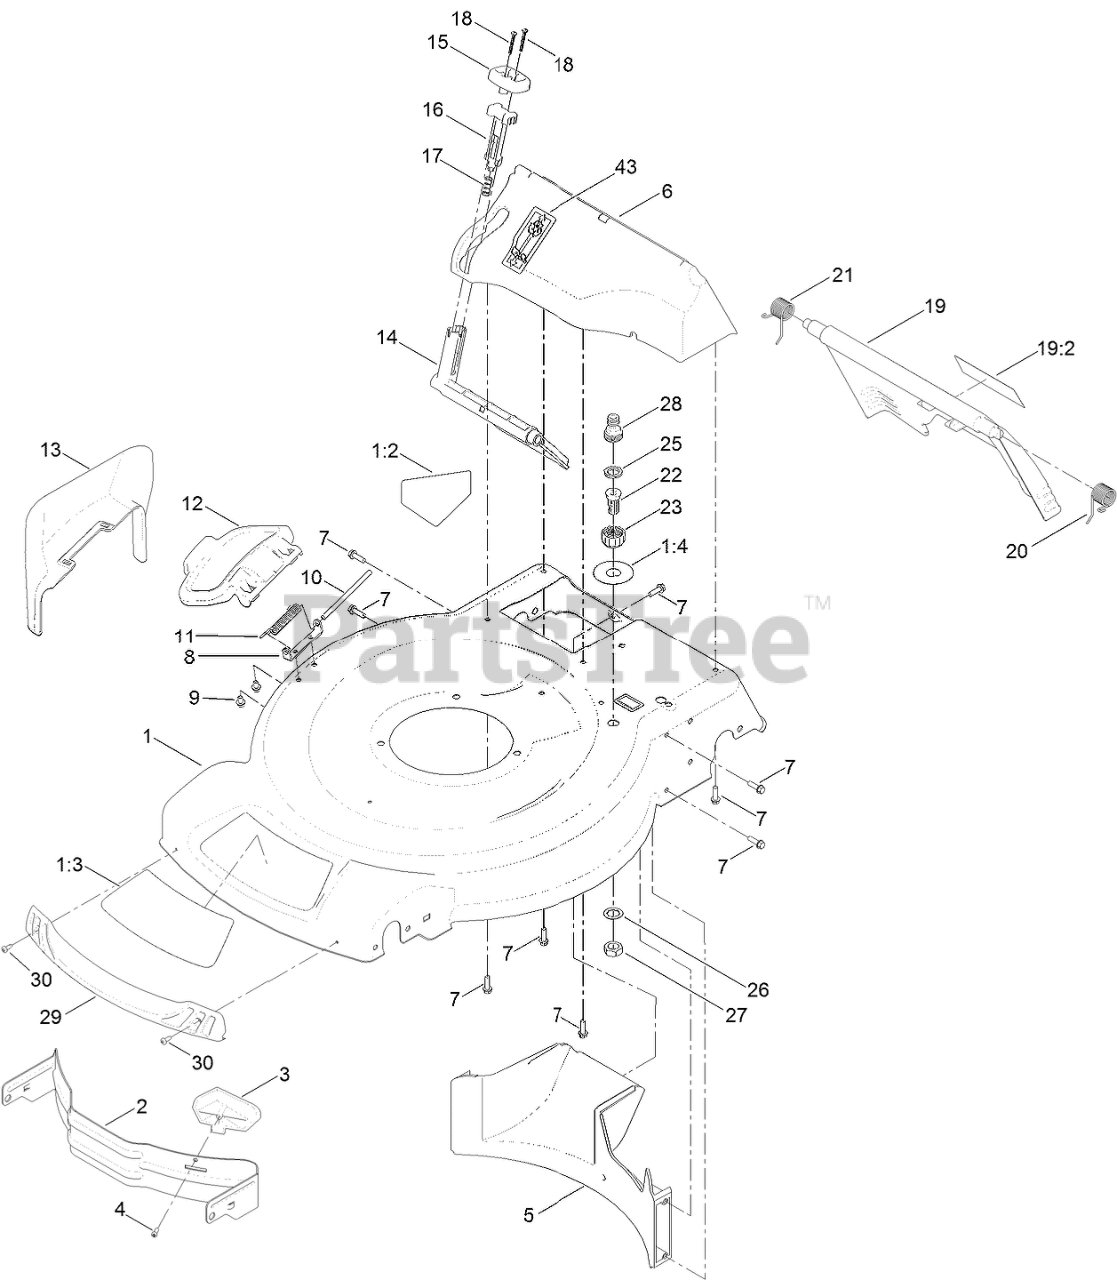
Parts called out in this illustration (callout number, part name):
1	HOUSING ASM
1:2	DECAL-DANGER
1:4	DECAL-PORT, WASHOUT
2	BAFFLE-FRONT
3	KICKER-FRONT
4	SCREW-PPH
5	BAFFLE-REAR
6	CHUTE-RECYCLE
7	SCREW-HWH
8	BRACKET-COVER
9	SCREW-HWH
10	ROD-COVER
11	SPRING-TORSION
12	DEFLECTOR-SIDE
13	CHUTE-DISCHARGE, SIDE
14	DEFLECTOR-RECYCLE
15	KNOB-RECYCLE
16	LATCH-RECYCLE
17	SPRING-COMPRESSION
18	SCREW-PPH
19	REAR DOOR ASM
19:2	DECAL-WARNING
20	SPRING-TORSION
21	SPRING-TORSION
22	PORT-WASHOUT
23	COUPLING-HOSE, WASHOUT PORT
25	WASHER-SEAL, WASHOUT PORT
26	WASHER-TOOTH, INTERNAL
27	NUT-JAM
28	ADAPTER-CONNECT, QUICK
29	BUMPER
30	SCREW-FORMING, THREAD
